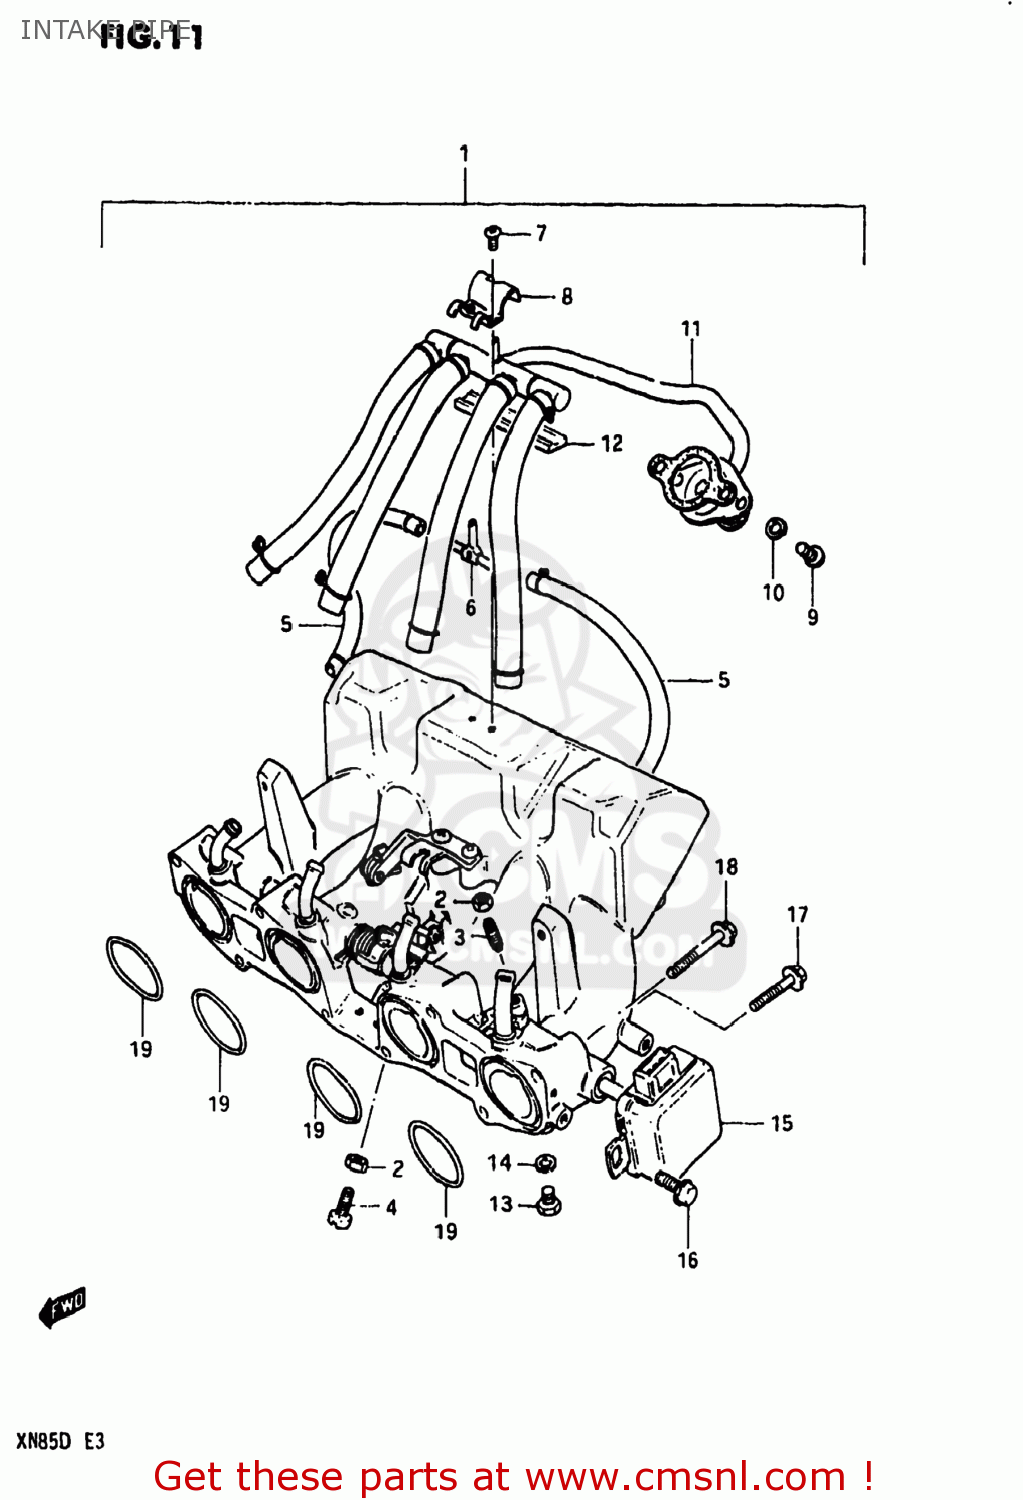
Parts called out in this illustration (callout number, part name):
1	MANIFOLD,INTAKE
2	NUT
3	SCREW
4	SCREW
5	HOSE
6	PIPE
7	SCREW
8	PLATE
9	SCREW 6X12
10	LOCK WASHER
11	SWITCH,CARBURETOR HEATER THERMOSTAT
12	SEAT, RUBBER
13	PLUG,DRAIN
14	WASHER,DRAIN PLUG
15	SENSOR ASSEMBLY,THROTLLE P
16	BOLT
17	BOLT
18	BOLT
19	O RING(D:2.4,ID:37.7)
